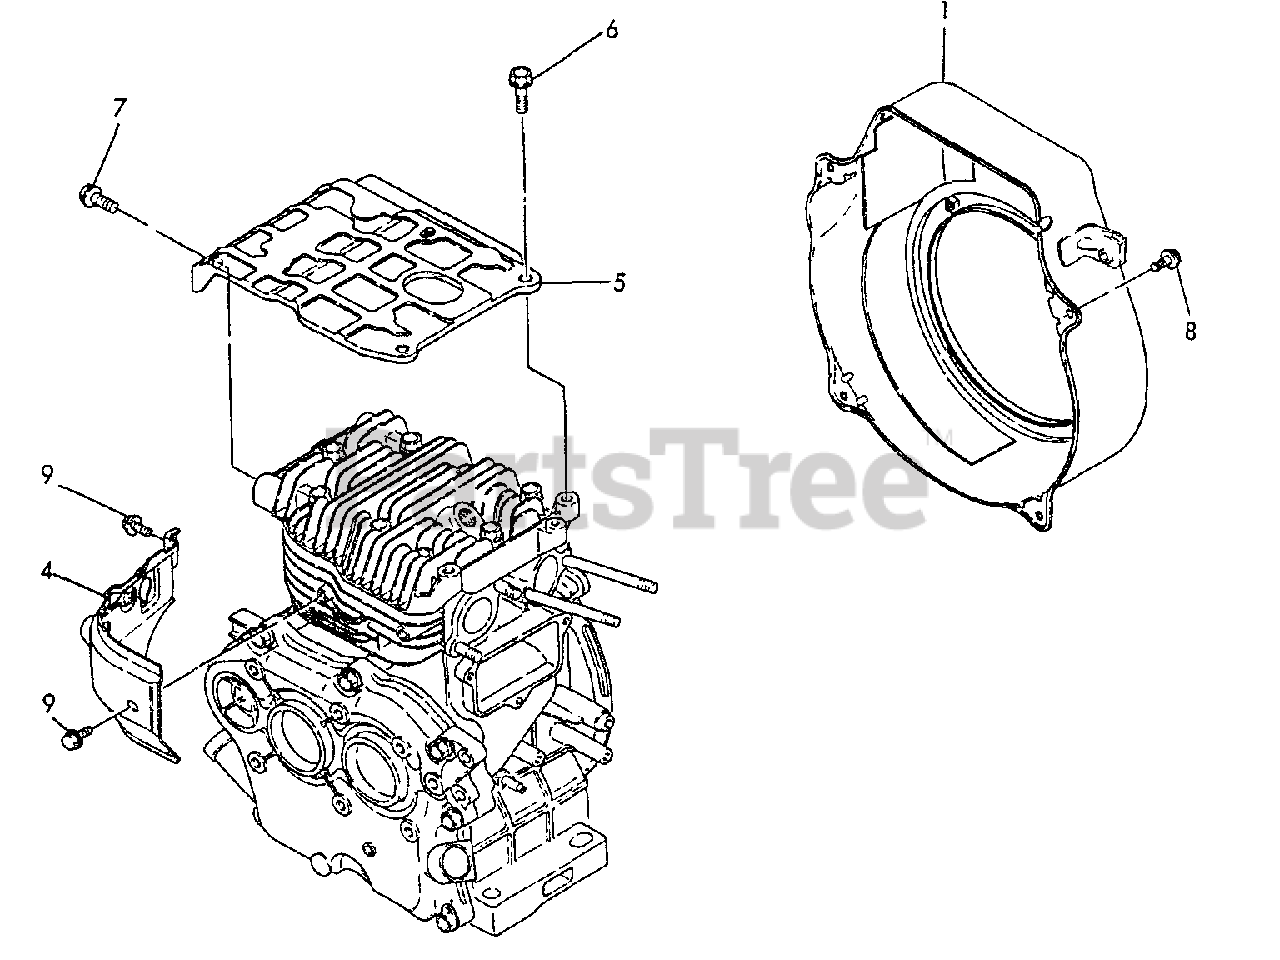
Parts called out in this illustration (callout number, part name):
1	COVER, FAN
4	SHIELD, CYLINDER
5	COVER, HEAD
6	BOLT - 8X14 -- PLATED
7	BOLT - 8X20 -- PLATED
8	BOLT - 6X8 -- PLATED
9	BOLT - 6X8 -- PLATED
